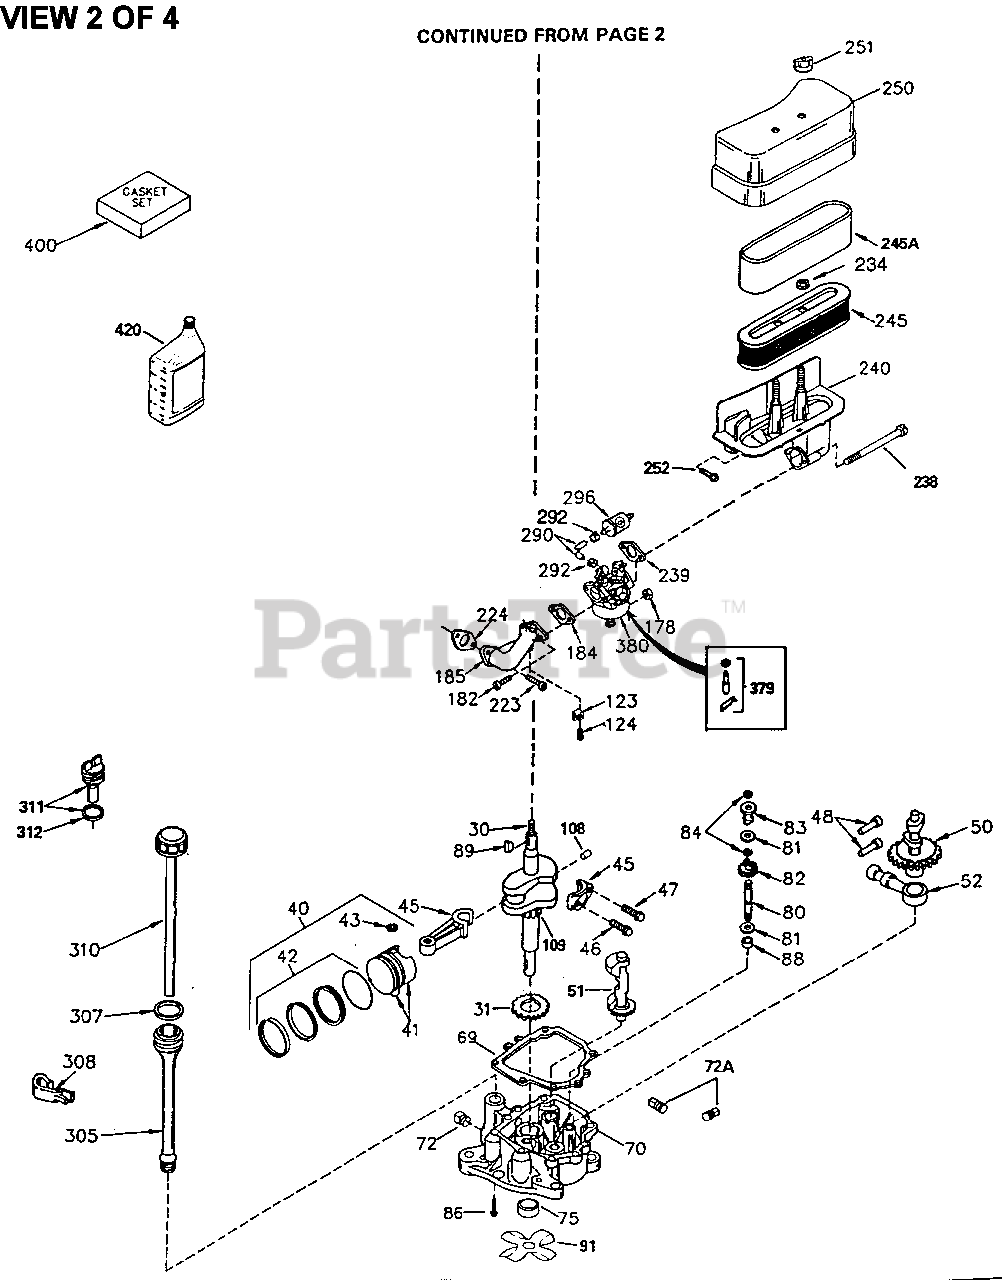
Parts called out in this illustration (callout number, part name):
30	Crankshaft
31	Counterbalance Gear
40	Piston, Pin & Ring Set (Std.)
40	Piston, Pin & Ring Set (.010" OS)
40	Piston, Pin & Ring Set (.020" OS)
41	Piston & Pin Ass'y. (Std.) (Incl. 43)
41	Piston & Pin Ass'y. (.010" OS) Incl. 43
41	Piston & Pin Ass'y. (.020" OS) Incl. 43
42	Ring Set (Std.) (3-5/16")
42	Ring Set (.010" OS)
42	Ring Set (.020" OS)
43	Piston Pin Retaining Ring
45	Connecting Rod Ass'y. (Incl. 46 & 47)
46	Connecting Rod Bolt
47	Connecting Rod Bolt
48	Valve Lifter
50	Camshaft (MCR)
51	Counterbalance Weight
52	Oil Pump Ass'y.
64	Screw, T-30, 1/4-20 x 1/2"
69	* Mounting Flange Gasket
70	Mounting Flange (Incl. 72, 72A, 75 & 80)
72	Oil Drain Plug
75	Oil Seal
80	Governor Shaft
82	Governor Gear Ass'y. (Incl. 81)
83	Governor Spool
84	Retaining Ring
86	Screw, 1/4-20 x 1-3/16"
88	Spacer (Incl. 81)
89	Flywheel Key
123	Intake Pipe Brace
124	Screw, 1/4-20 x 5/8"
178	Nut & Lock Washer 1/4-28
182	Screw, 1/4-28 x 1"
184	* Carburetor To Intake Pipe Gasket
185	Intake Pipe
223	Screw, Torx T-30, 5/16-18 x 1-1/8"
224	* Intake Pipe Gasket
238	Screw, 10-32 x 1-17/32"
239	* Air Cleaner Gasket
240	Air Filter Body (Incl. 239)
245	Air Filter (Incl. 234) also available in Packaged Part #740015B
245A	Pre-Cleaner Air Filter also available in Packaged Part #740015B
250	Air Cleaner Cover
251	Wing Nut, 1/4-20
251A	Nut & Lock Washer, 1/4-20
290	Fuel Line (8.62")
292	Fuel Line Clamp
296	Fuel Filter (Incl. 292) also availabl e as Packaged Part #740003B
305	Oil Fill Tube
307	"O" Ring
308	Fill Tube Clip
310	Dipstick
380	Carburetor (Incl. 184)
393	Cup & Screen
400	* Gasket Set (Incl. items marked PK in notes) Incl. part #'s 26756 (1), 2727 2A (2),27896A (2),27915A (1),29673 (1 ),33263 (1),33629 (1),34041A (1) ,343 27A (1),34698A (1),34912 (1),34923A ( 1),35262 (1),35317 (1),35865 (1)
